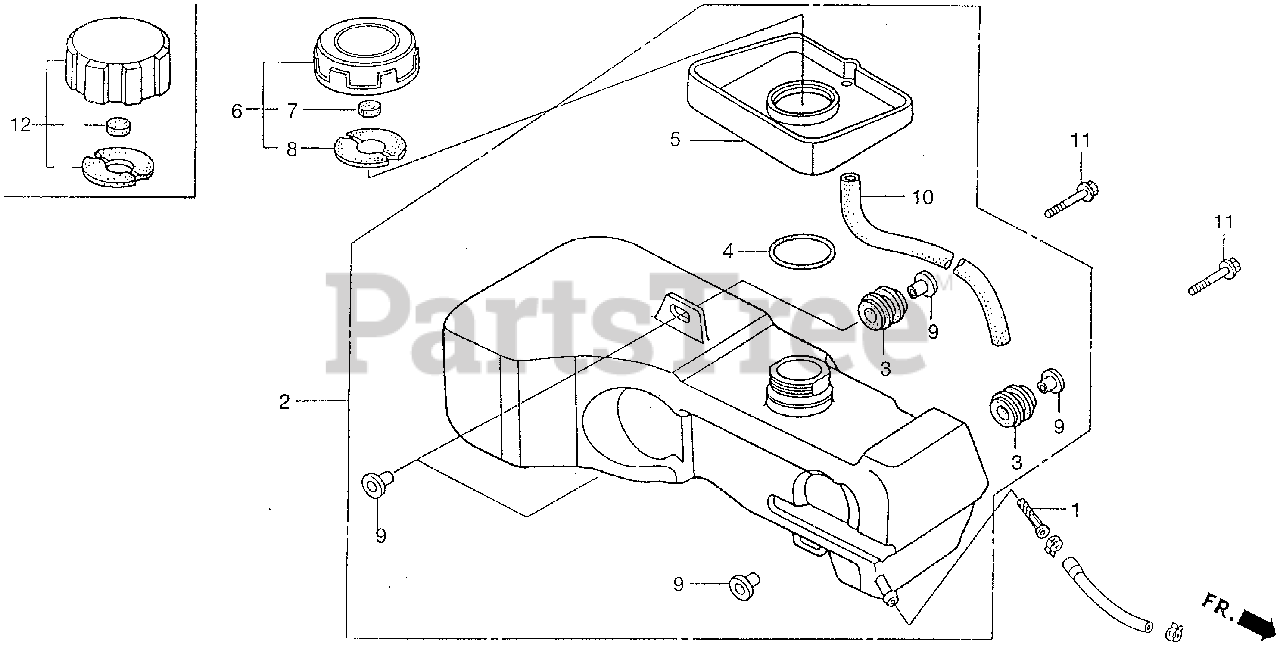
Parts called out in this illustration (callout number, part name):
1	FILTER, FUEL
2	TANK ASSY., FUEL
3	RUBBER, TANK SETTING
4	O-RING (49.5X3.1)
5	TRAY, FUEL
6	CAP ASSY., FUEL TANK
7	SPONGE, FUEL CAP BREATHER
8	GASKET, FUEL CAP
9	COLLAR, FUEL TANK
10	BULK HOSE, VACUUM (12X1000) (12X340)
11	BOLT, FLANGE (6X32)
12	CAP ASSY., FUEL TANK
